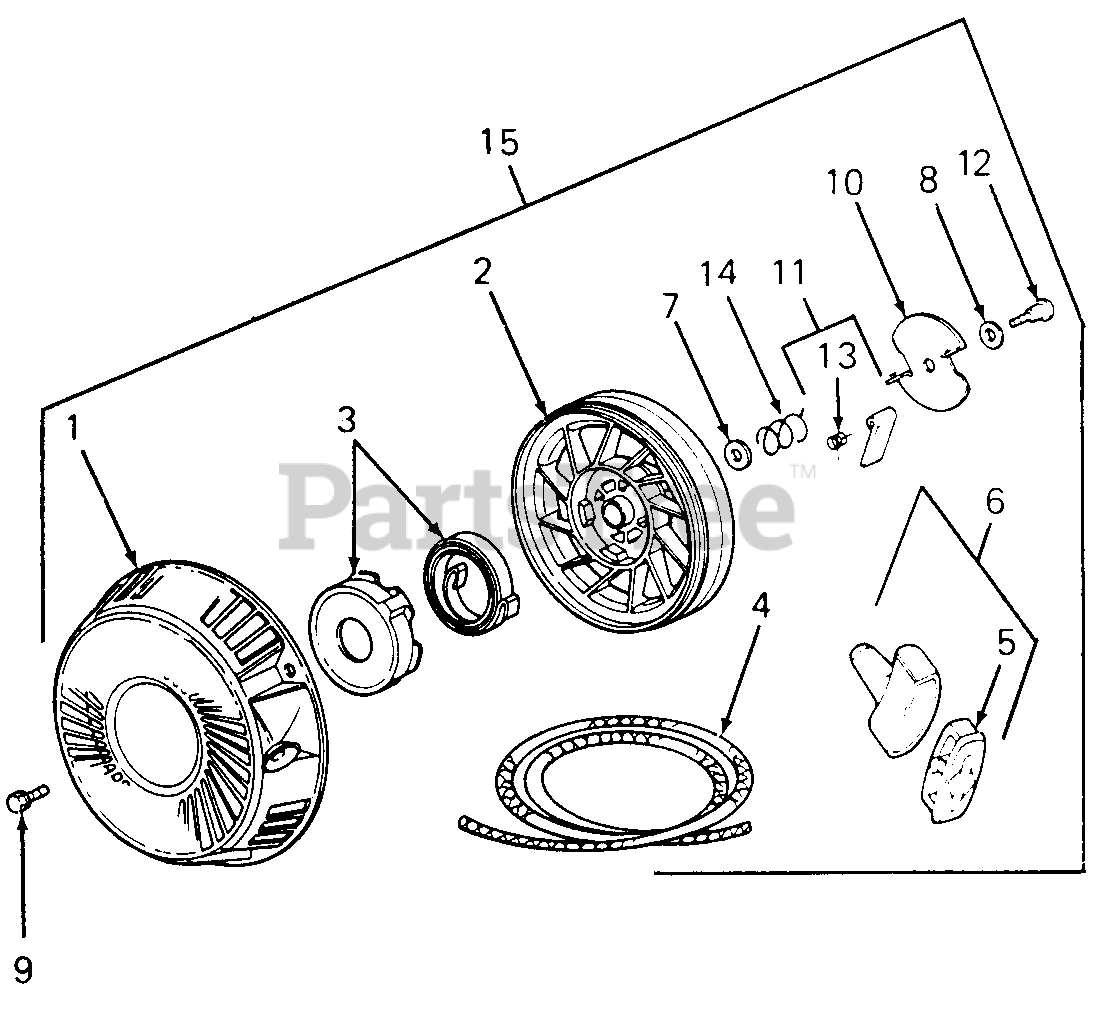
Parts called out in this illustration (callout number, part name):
1	Housing, Starter
2	Pulley, Rewind Starter
3	Spring, Rewind Starter
4	Rope, Starter
5	Insert, Handle
6	Grip, Starter
7	Washer, Pulley
8	Washer, Retainer
9	Screw, Sems
11	Armature
12	Screw, Retainer
13	Spring, Dog
14	Spring, Torsion
15	Starter Assy
